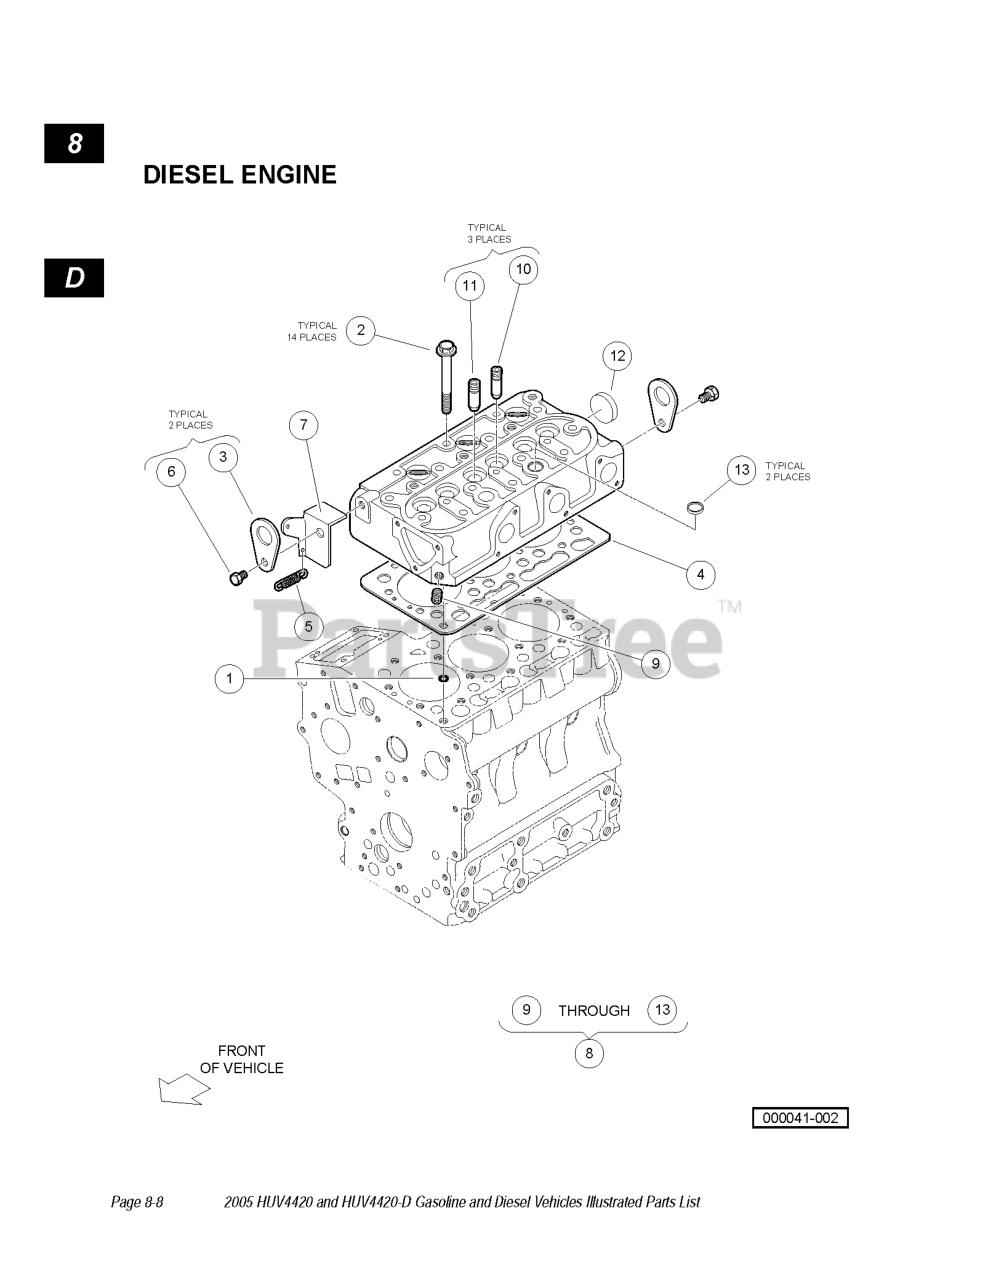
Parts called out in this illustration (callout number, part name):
1	O-RING, 8 X 7
2	BOLT, CYLINDER HEAD
3	HOOK, ENGINE
4	GASKET, CYLINDER HEAD
5	SPRING, START
6	BOLT, ENGINE HOOK
7	STAY, CYLINDER HEAD
8	CYLINDER HEAD, COMP, D722 CB
9	PLUG, 3/32" NPT
10	GUIDE, EXHAUST VALVE
11	GUIDE, INLET VALVE
12	CAP, SEALING, HEAD
13	CAP, SEALING, HEAD, TOP
